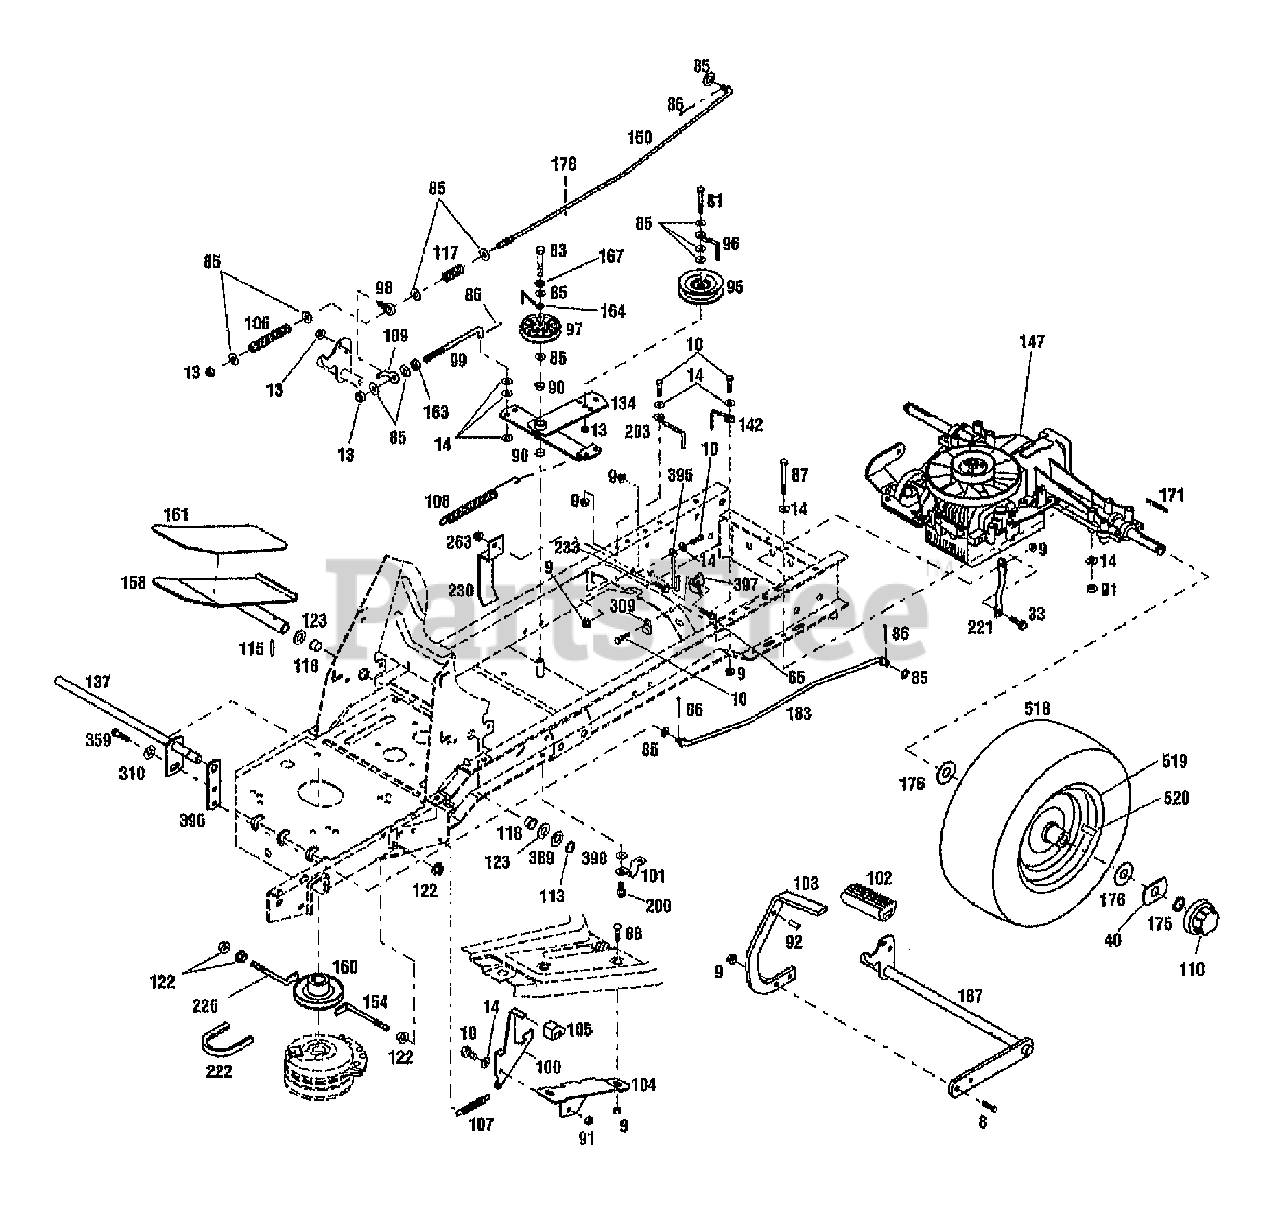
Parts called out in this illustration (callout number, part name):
8	SCR-HH 5/16-18X1.0 G5 ZP
9	NUT-HFLK 5/16-18 ZP
10	SCR-HHC 5/16-18X.75 GR 5 ZP
13	NUT-LOCK 3/8-16
14	WASHER-FLAT 5/16 SAE
33	SCR-HFLK 5/16-18X.75
40	WASHER-SPEC .75X2.50
65	SCR-HH 1/4-20X.625
81	SCR-HH 3/8-16X2.0 G5 ZP
83	SCR-HH 3/8-16X1.75 G5 ZP
85	WASHER-FLAT 3/8 SAE
86	PIN-COTTER .09X.75 ZP
87	SCR-HH 5/16-18X2.75 G5 ZP
88	SCR-CARR 5/16-18X.62 G2 ZP
90	BUSHING-.5X.5 NYLON FLNG
91	NUT-TOP/LK 5/16-18 ZP
92	PIN-DRIVE .312X.75
96	GUIDE-BELT
97	PULLEY-IDLER
98	BOLT-EYE
99	ROD-CLUTCH
100	LATCH-BRAKE LOCK
101	CLIP-CLAMP .75 ID
102	PAD-FOOT PEDAL
103	PEDAL-BRAKE
104	BRKT-BRAKE LOCK
105	PAD-BRAKE
106	SPRING-COMPRESSION
107	SPRING-EXTENSION
108	SPRING-EXTENSION
109	ROD-PIVOT
110	CAP-HUB
113	RING-RETAIN .625 ID
115	PIN-ROLL .188X1.0
117	SPRING
118	BEARING-FLANGE
122	NUT-HFLK 3/8-16 ZP
123	WASHER-1.115X.637X.06
134	ARM-IDLER
137	SHAFT-HYDRO PIVOT
142	GUIDE-BELT
147	TRANSAXLE-HYDRO
150	ROD-BRAKE
154	RETAINER-CLUTCH
158	ASSM-PEDAL HYDRO
160	PULLEY-ENGINE
161	PAD-FOOT PEDAL
163	NUT-HEX 3/8-16 ZP
164	GUIDE-BELT
167	WASHER-LK .375 @ DEPL
171	KEY-3/16X3/16X1 3/4
175	RING-RET."E".577 ID
176	WASHER-1.87X.765X.06 SPECIAL
178	PIN-DRIVE .09X.75
183	ROD-HYDRO CONTROL
187	ASSM-BRAKE PEDAL
200	SCR-HFLK 5/16-18X.75
203	GUIDE-BELT
221	SUPT-TRANSMISSION
226	GUIDE-BELT
233	SCR-HFLK 5/16-18X.62 G5ZP
263	NUT-HFT/LK
309	CLIP-J
310	WASHER-LK .375 PYRAMIDAL
359	SCR-HH 3/8-16X.88 G5 ZP
389	WASHER-1.0X.64X.029
390	WASHER-.632X.39X.0329
395	GUIDE-BRAKE ROD
396	ARM-CONTROL
518	TIRE-20X8.00-10
519	WHEEL-REAR
520	STEM-VALVE
